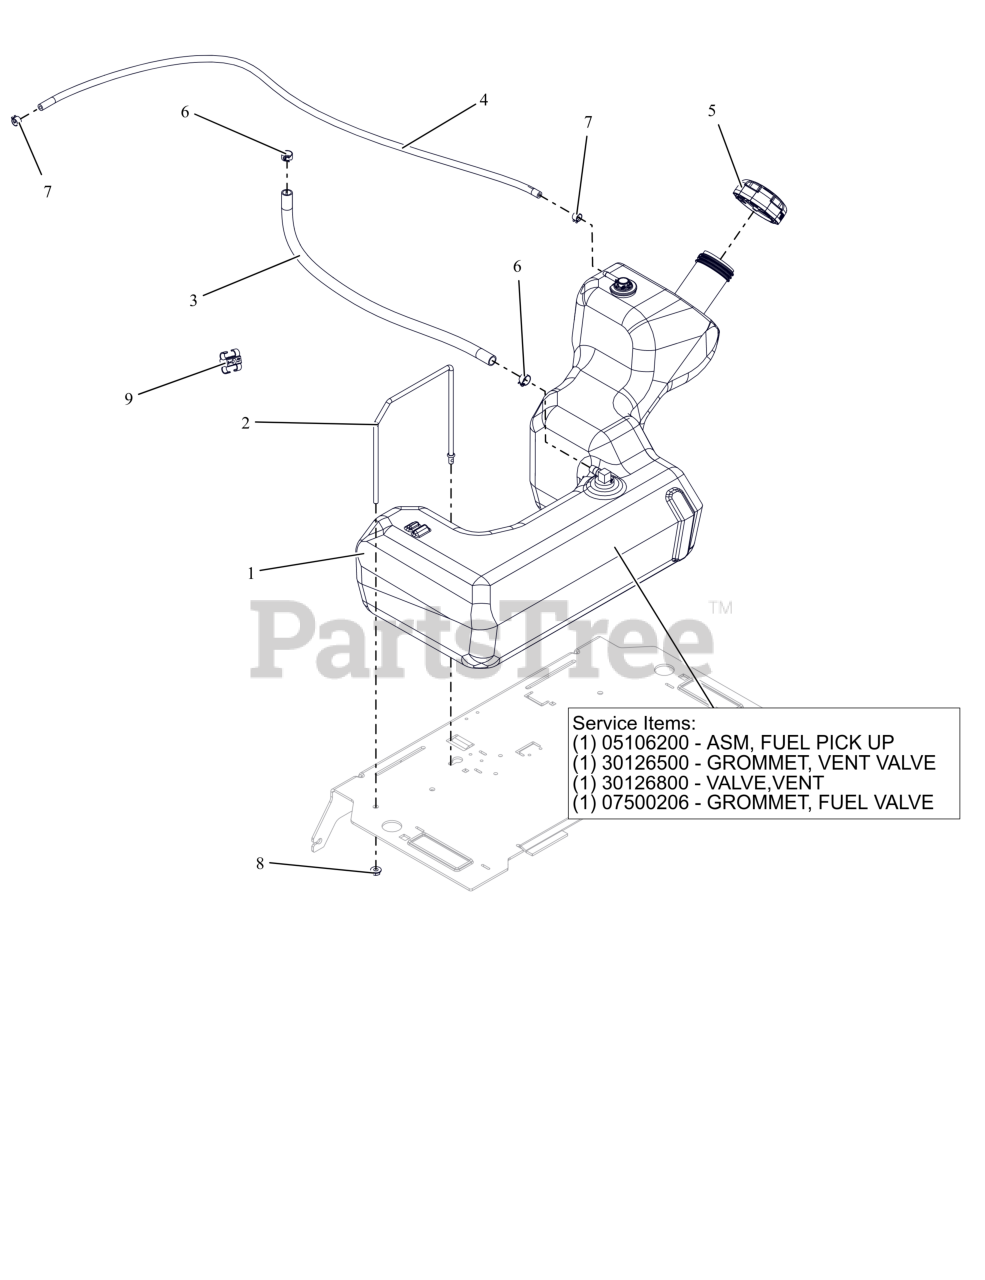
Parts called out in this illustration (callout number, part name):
1	ASM, FUEL TANK - IKON 23
1	ASM, IKON FUEL PICK-UP
1	GROMMET, VENT VALVE
1	VALVE, VENT
1	BSHG-FLG .375X1.062X.625 NITR
2	STRAP, TANK HOLD DOWN
3	1 INCH OF HOSE, .25 LOW-PERM BULK GAS
4	HOSE, .188 30R7 BULK
5	CAP-FUEL- 2.25 RATCHET INLET V
6	CLAMP, FUEL LINE
7	CLAMP-HOSE, SPRING .188
8	NUT-LK-CTR-FLG .25-20 ZC120
9	CLIP, T, .38-.50
